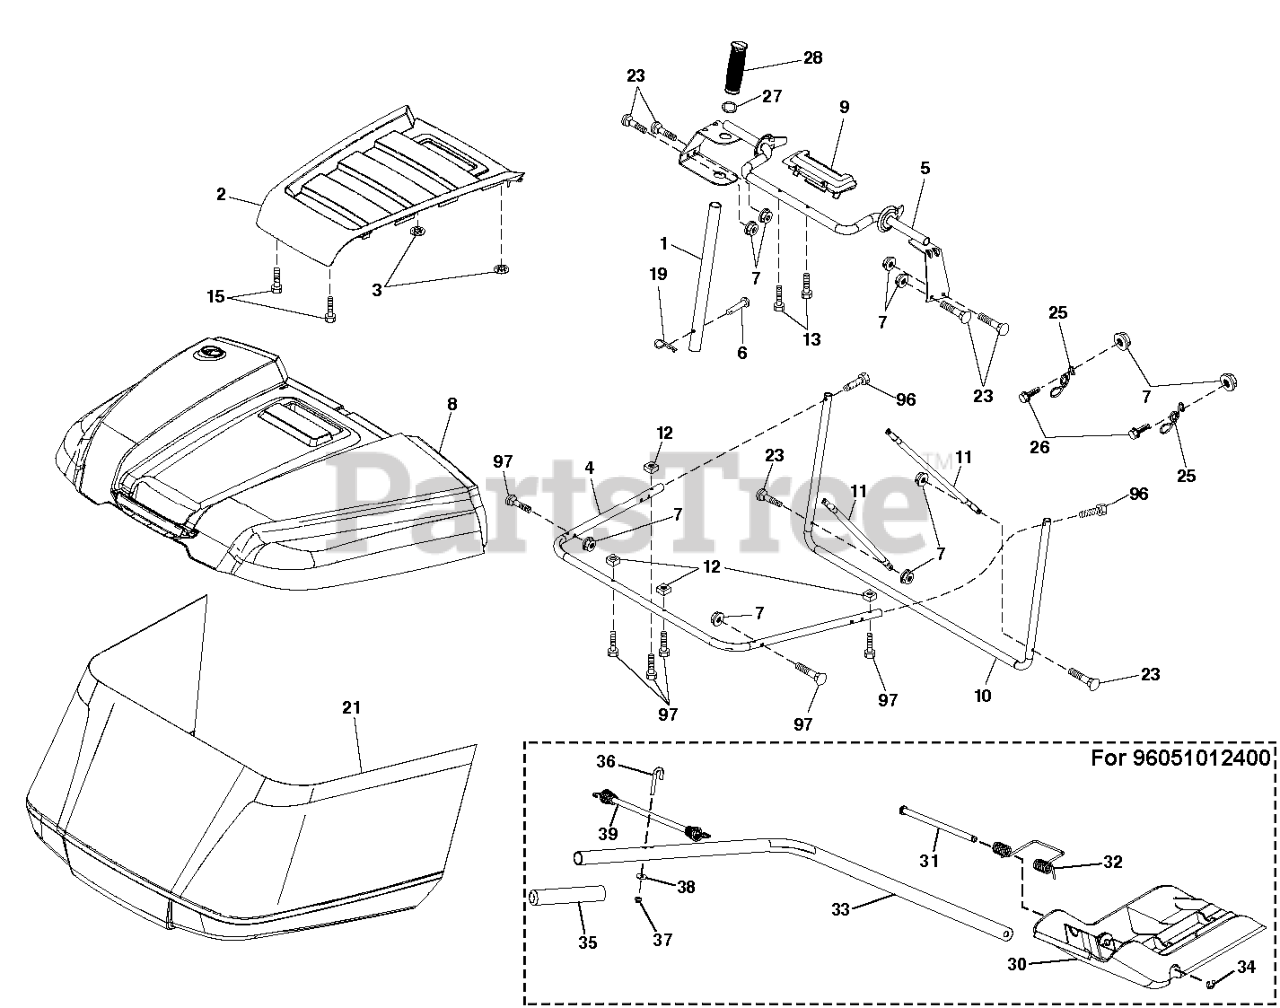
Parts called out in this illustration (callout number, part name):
1	TUBE.HANDLE.BAGGER.CRD/SRD.BLA
2	APPLIQUE.TOP.BAG.SRD.ORANGE
3	NUT.PUSH.156
4	SUBASM.TOP.BAGGER.TUBE
5	FRAME.ASM.TOP.BAGGER.SRD
6	RIVET,DRILLED
7	NUT T
8	BAGGER.TOP.SRD.APPLIQUE
9	INSERT.HANDLE.BAGGER.(2 2)
10	FRAME FRAME.FRONT.TEX.CRD
11	BRACE BRACE SIDE TUBE
12	NUT.SQUARE.1/4
13	SCREW.1/4X1.150.HXWSH
15	SCREW,#8.FLAT.HEAD.DRILL.TIP
19	PIN.COTTER.5/16.BOW TI
21	BAG SUBASM. TEX CRD GEN 2 HUSQ
25	SPRING.LATCH.BAGGER.SRD
26	SCREW HEX CRT
27	RB GROMMET.RUBBER.SRD
28	GRIP.HANDLE.BLACK
30	PLUG PLUG
31	PIN PIN.HINGE
32	SPRING SPRING DOUBLE TORSION
33	SHAFT SHAFT TEX CRD MULCH PLU
34	E-RING.5/16"
35	GRIP GRIP MULCH PLUG HAND
36	BOLT BOLT J
39	BUBGEE BUBGEE TEX CRD
96	SCREW.HEXCAP.1/4X-20X1.500
97	SCREW.HEXCAP.1/4X-20X1.500
97	SCREW.TORX.BUTN.HD.1/4-20-1.5"
